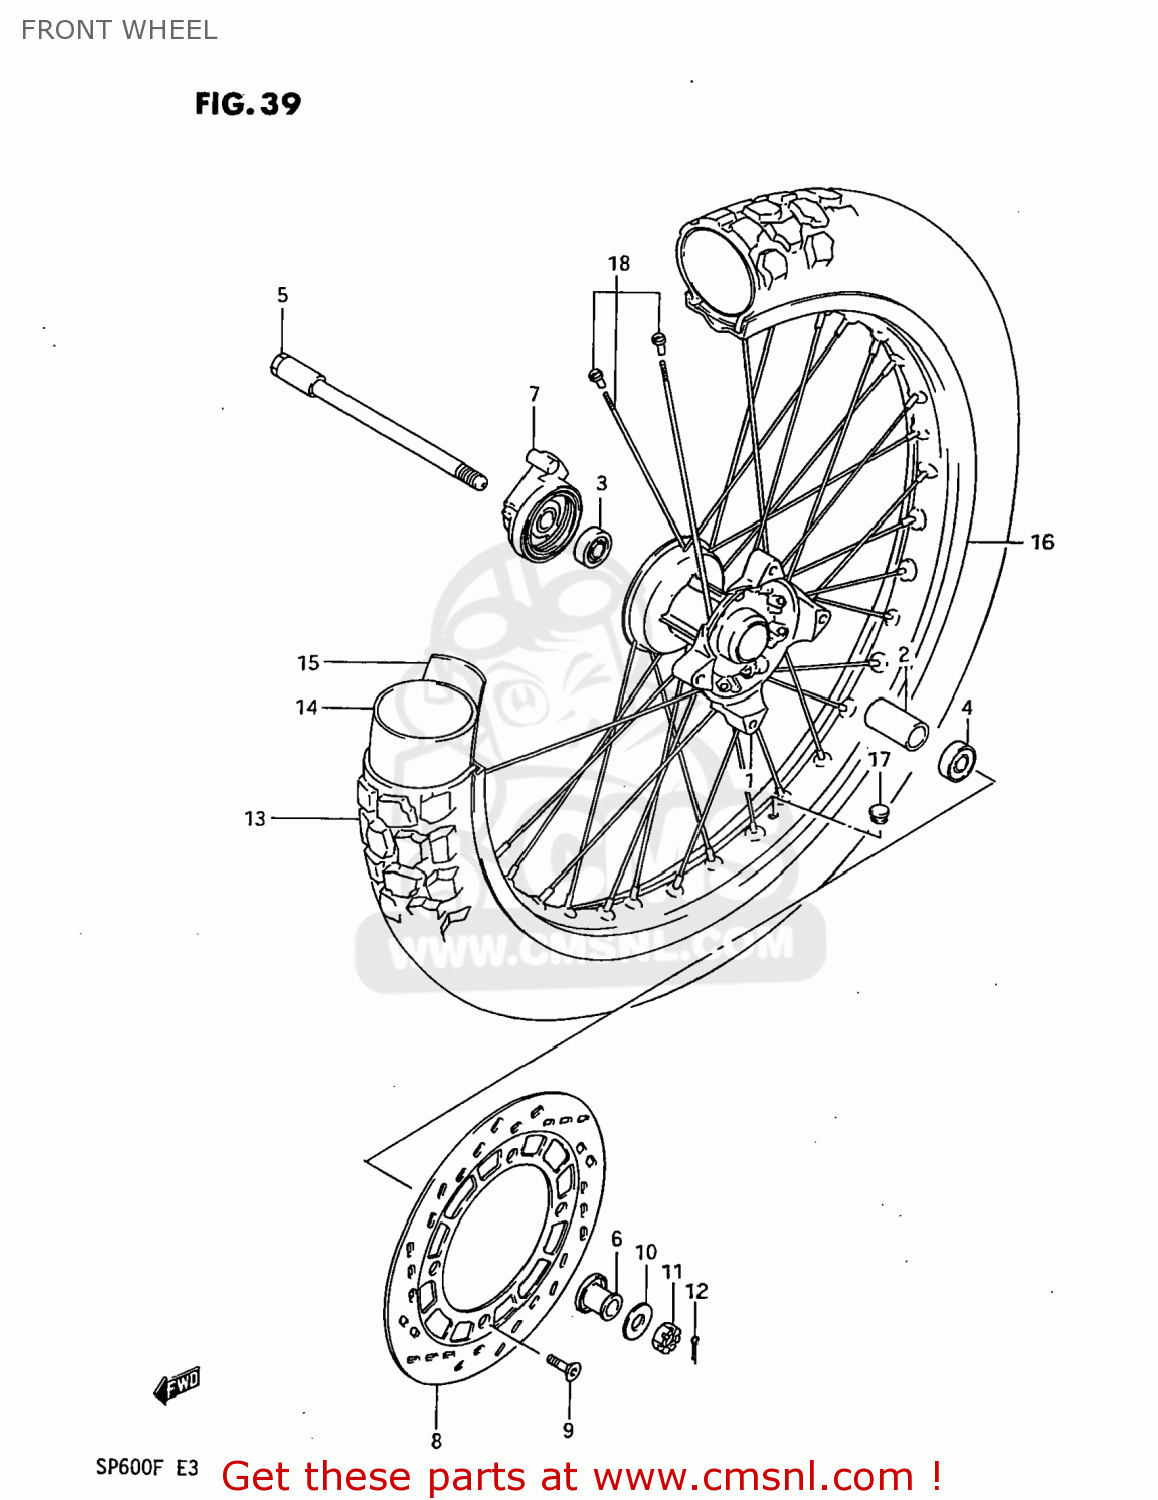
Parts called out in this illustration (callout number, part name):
1	HUB,FRONT
2	SPACER(15.3X21.7X56)
3	BEARING
4	BEARING
5	AXLE,FRONT
6	SPACER,FRONT AXLE,LEFT
7	BOX ASSEMBLY,SPEEDOMETER GEAR
8	DISC,FR BRAKE
9	BOLT,BRAKE DISC
10	WASHER
11	NUT 12MM
12	COTTER PIN
13	TIRE 100/80-21
14	TUBE,INNER
15	PROTECTOR,WHEEL,INNER
16	RIM,FRONT WHEEL (1.85X21)(
17	CAP(OD:12)
18	SPOKE SET,FRONT
